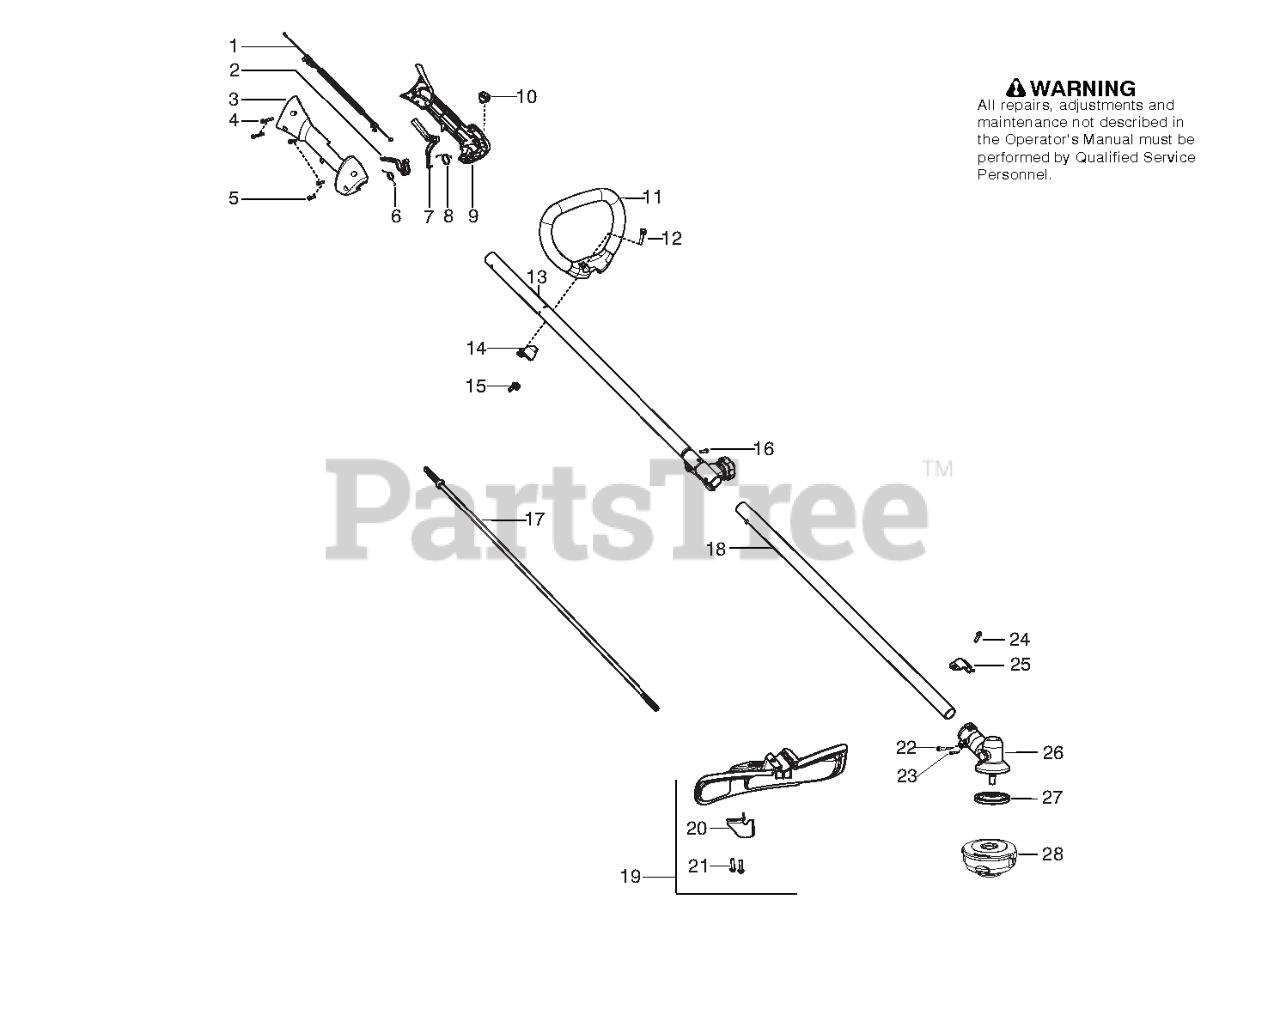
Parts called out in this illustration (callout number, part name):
1	ASSY-CABLE WIRE HARNESS
2	TRIGGER THROTTLE
3	HOUSING-THROTTLE RH
5	SCREW M4 X 1.75 PT 16MM
6	SPRING TRIGGER
7	THROTTLE LOCKOUT
8	SPRING LOCKOUT
9	HSG THROTTLE LH
10	KIT SWITCH
12	BOLT, TYPE 2
13	KIT DRIVESHAFT UPPER SHAFT
14	CLAMP ASSIST HANDLE
15	WINGNUT, TYPE 2
18	KIT LOWER SHAFT
19	KIT COBI SHIELD
20	Limiter - Line
22	SCREW - CARB. ADAPTOR
24	SCREW 1/4-20 X 7/8 (TAP
25	BRACKET SHIELD STRAIGHT SHAFT
26	ASSY GEARBOX
27	DRIVE DISC
28	T25 TRIM HEAD 10MM LH
